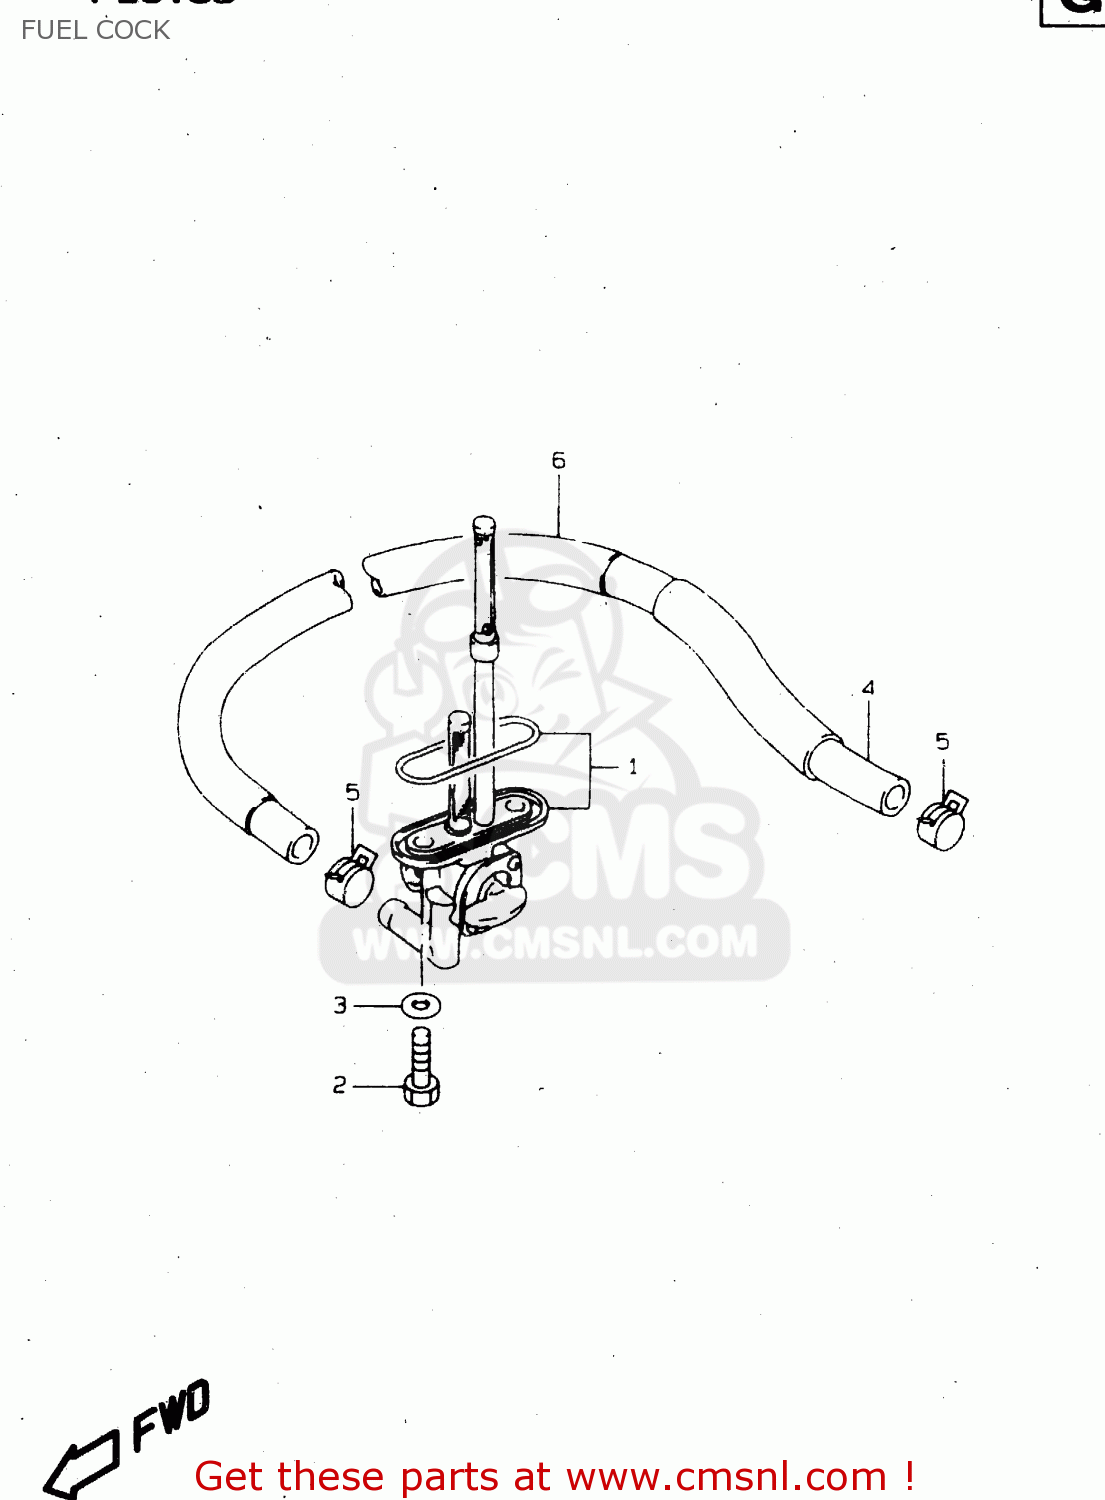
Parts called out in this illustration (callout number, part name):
1	COCK ASSY,FUEL
2	BOLT(6X20)
3	GASKET(6.4X11.5X0.8) (NAS)
4	HOSE,FUEL PUMP & COCK
5	CLIP
6	TUBE,FUEL HOSE
